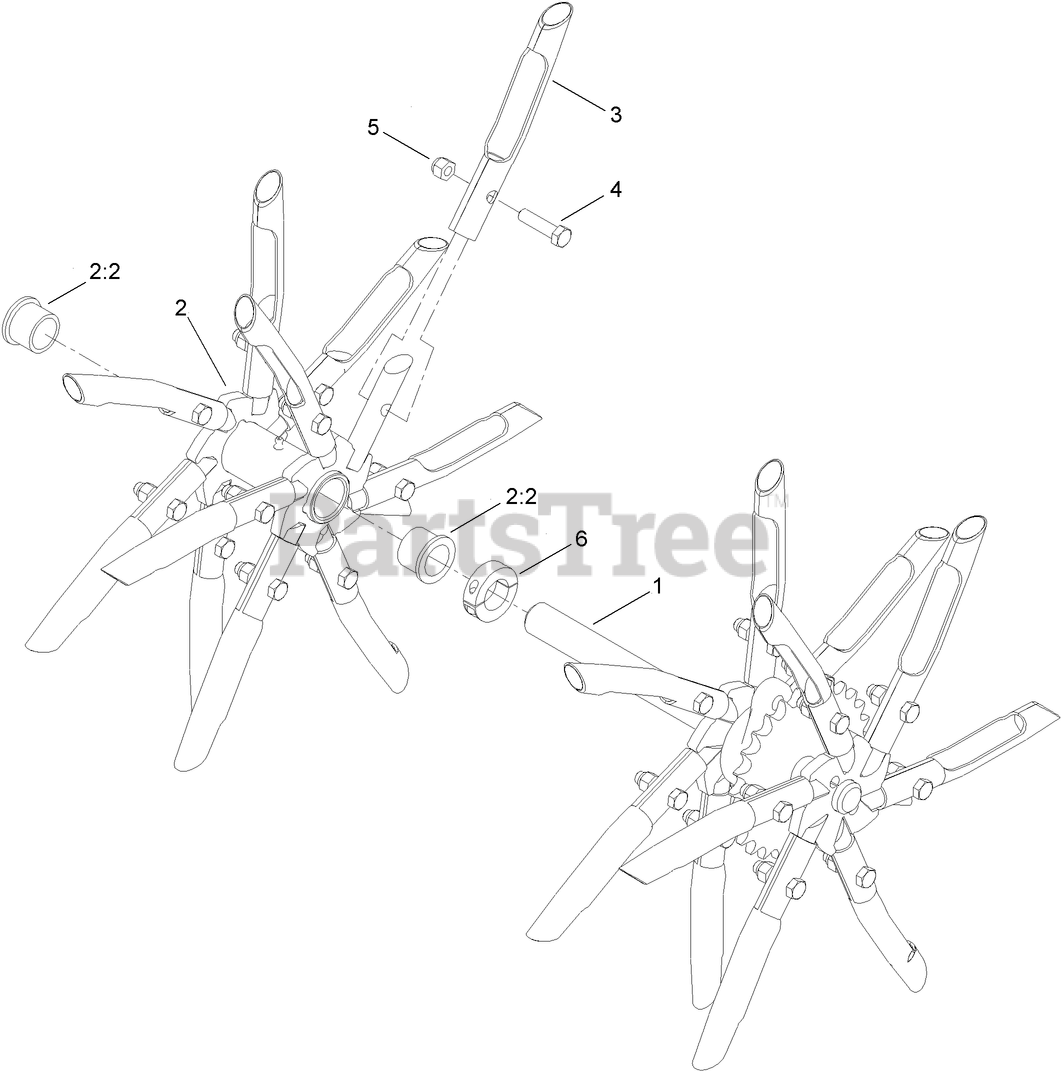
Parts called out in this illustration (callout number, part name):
1	SHAFT-TINE, LH
2	FLOAT TINE SHAFT ASM
2:2	BUSHING-FLANGE
3	TINE-CORING
4	SCREW-HH
5	NUT-LOCK, NI
6	COLLAR-LOCKING
